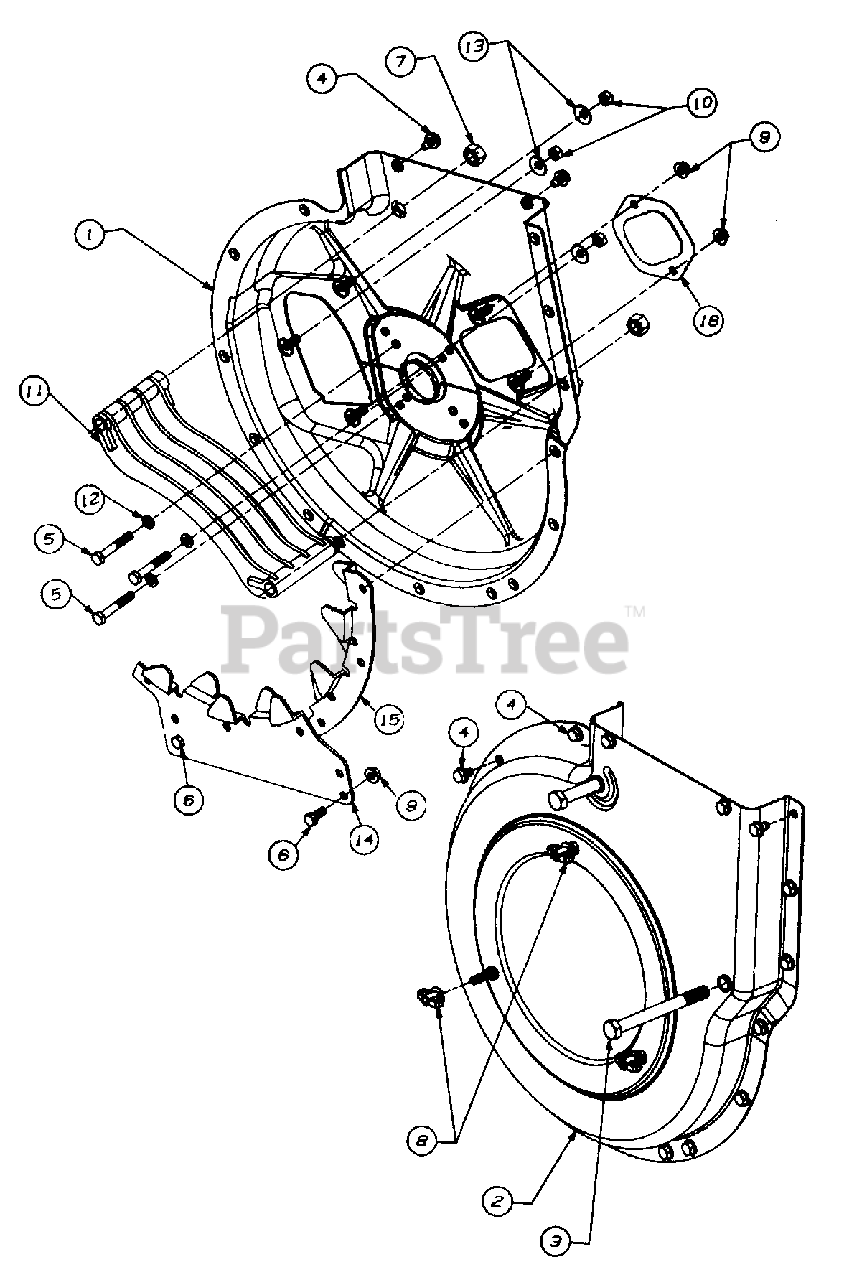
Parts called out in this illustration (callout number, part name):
3	SCREW - HEX
4	SCREW - HEX SELF TAP
5	SCREW - HEX
6	SCREW - HEX
7	NUT - HEX LOCK
9	NUT - HEX LOCK
10	NUT - HEX (GR 5)
11	SCREEN
12	WASHER - LOCK
13	WASHER - BELL
